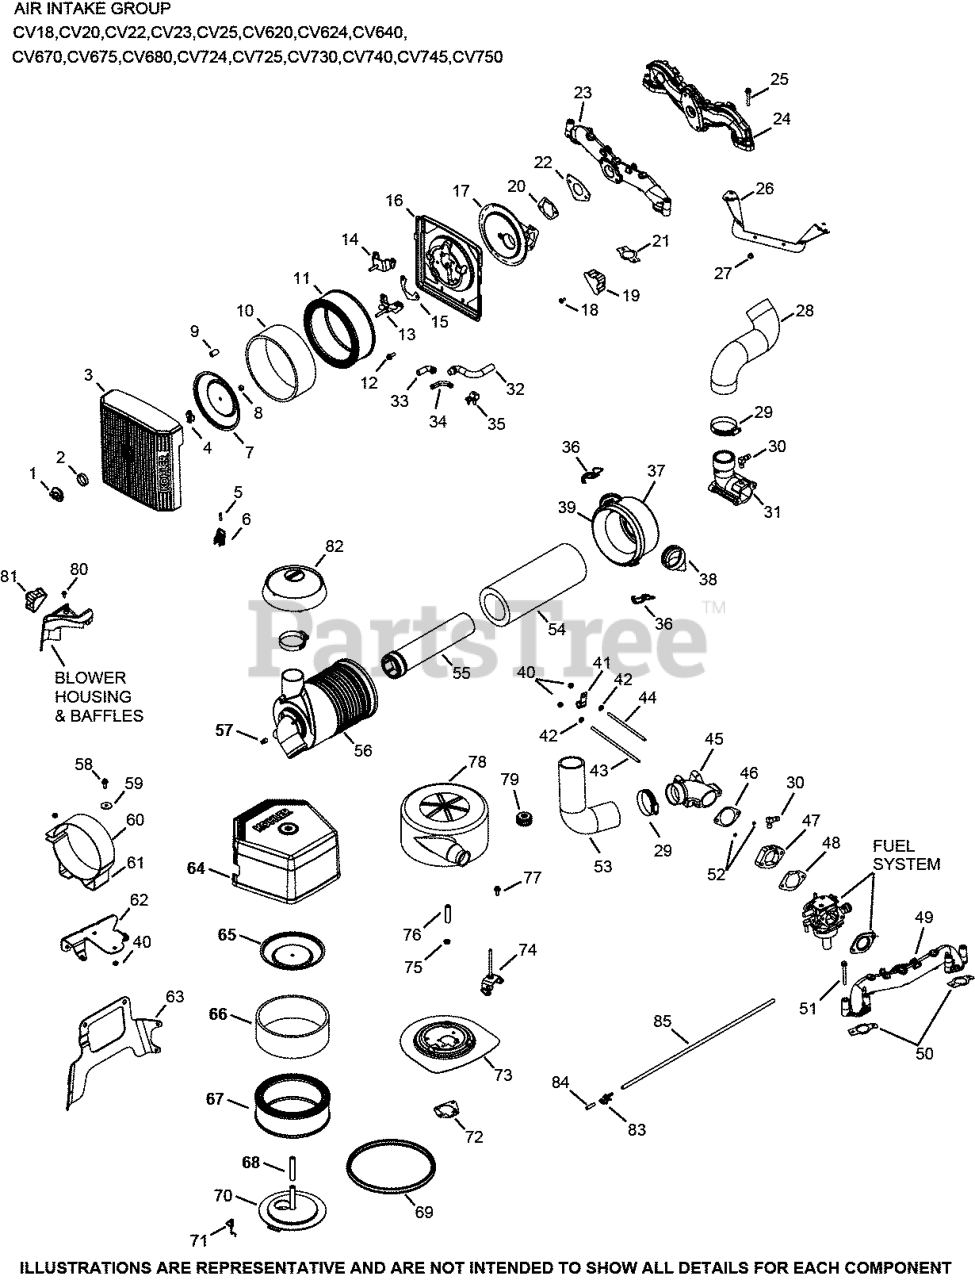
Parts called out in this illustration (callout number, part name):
2	CLAMP, HOSE
4	NUT, WING
7	COVER, INNER AIR CLEANER
10	ELEMENT, AIR FILTER (HIGH) - Also available Retail Packaged 24 883 03-S1 Air Filter Kit
19	COVER, BLOWER HOUSING USE 24 096 160-S
20	GASKET, AIR CLEANER BASE
21	GASKET, INTAKE MANIFOLD USE 24 041 79-S
51	SCREW, FLG M6X1.0X55
70	ELBOW, AIR CLEANER - (#24 054 32-S)
75	NUT, FLG M6X1.0
83	CONNECTOR, EVAPORATIVE
84	CAP, MASKING
85	HOSE, EVAPORATIVE 20" USE 24 326 143-S
